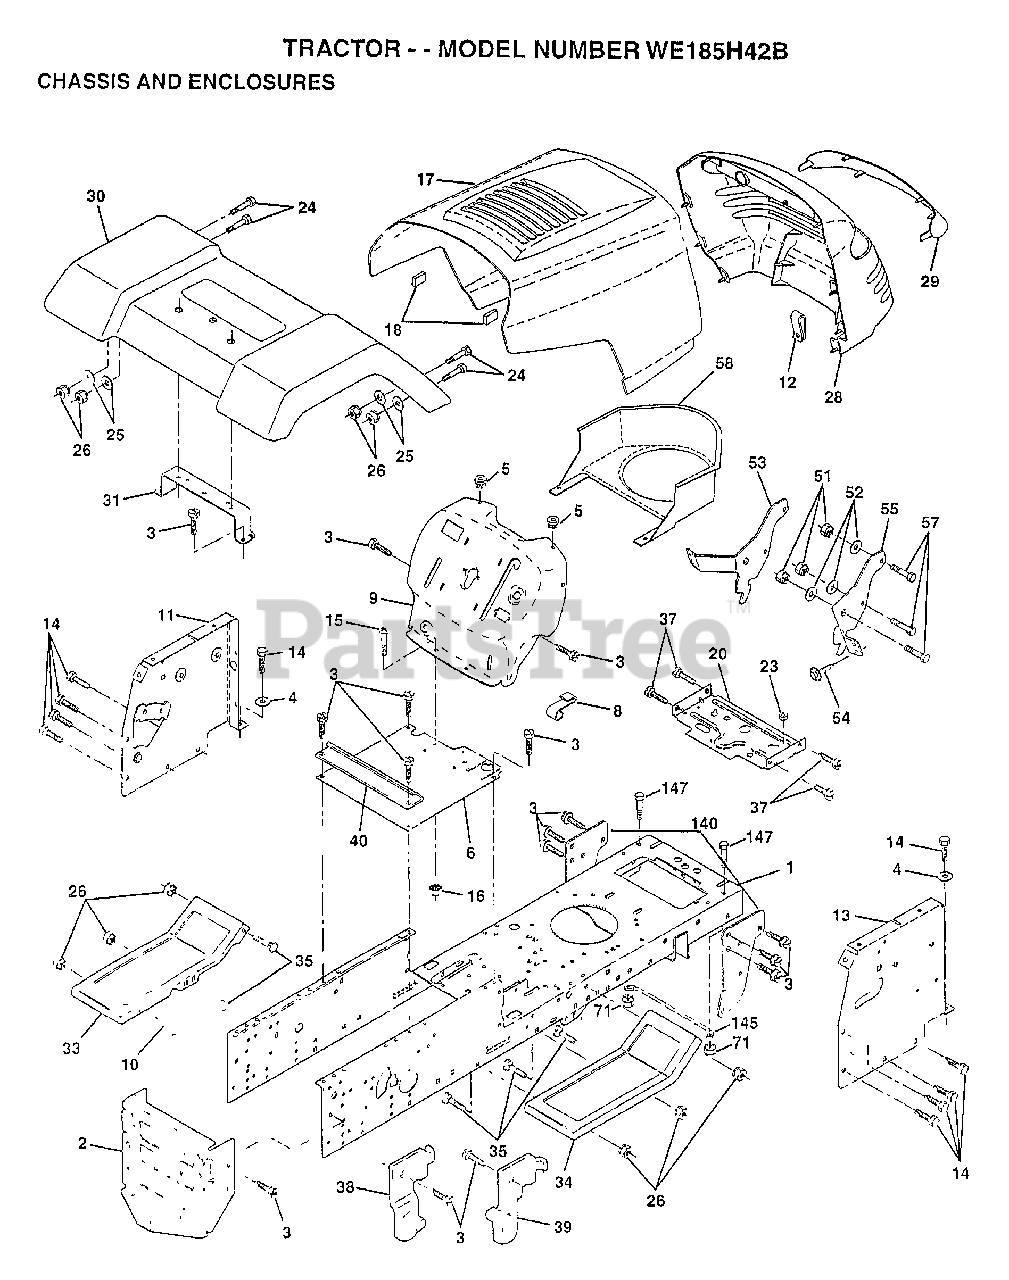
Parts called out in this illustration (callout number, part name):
1	CHASSIS ASM
3	SCREW
4	WASHER
5	BUMPER-HOOD/DASH
6	SADDLE
8	CLIP.RETAINER
9	DASH.SILKSCREENED
11	"PANEL-DASH,LH"
12	CLIP.TINNERMAN
14	SCREW LT
15	SCREW
20	"PLATE-MTG,BATT/FU"
24	BOLT
25	WASHER
26	NUT
28	GRILLE-MS428
29	LENS GRILLE
30	FENDER
31	BRACKET SUPT FEND
33	FOOTREST.LH.LT/GT
34	FOOTREST.RH.LT/GT
35	BOLT
37	SCREW LT
38	BRACKET ASM LH
39	BRACKET ASM RH
40	SPACER FENDER LT
51	NUT
52	WASHER
53	BRACKET.GRILLE.LH
55	BRACKET.GRILLE.RH
58	AIR DUCT
140	BRKT SUSPENSION
145	"ROD POVOT,CHASSIS"
147	BOLT LT
